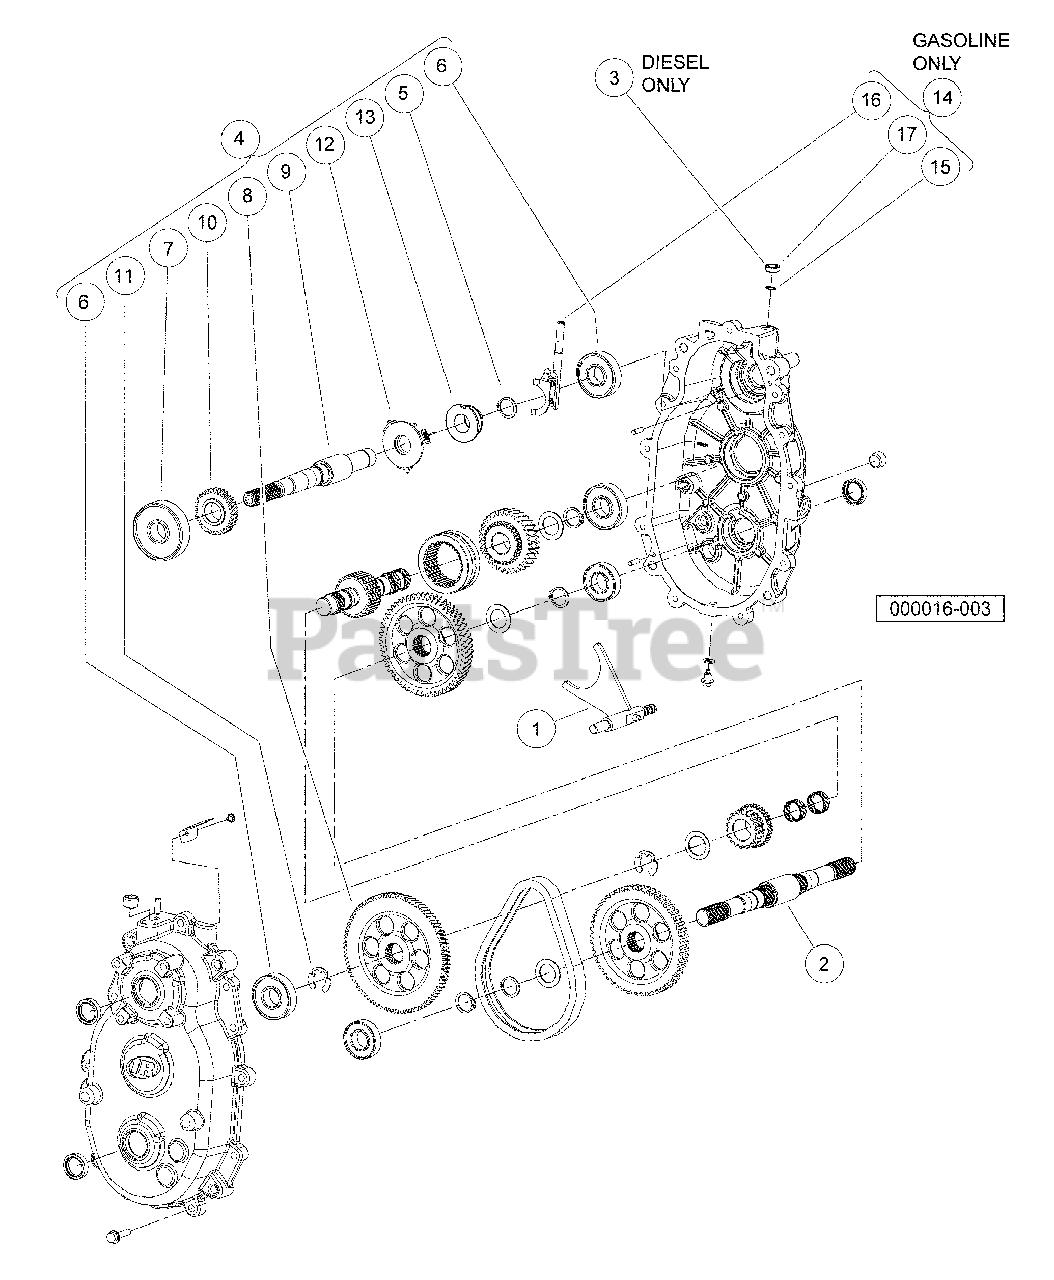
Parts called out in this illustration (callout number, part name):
1	Fork, Transmission
2	Shaft, Output
3	Plug, 19mm
4	Kit, Input Shaft Repair
5	Ring, Retaining, Basic External
6	Bearing, Ball
7	Bearing, Ball
9	Shaft, Input
11	Ring, Retaining, E-Ring
12	Sub Assy, Fly Weight
13	Sub Assy, Governor Spool
14	Kit, Governor Shaft Repair
15	Ring, Retaining.
16	Assy, Governor Arm
17	Seal, Dual-Lip
